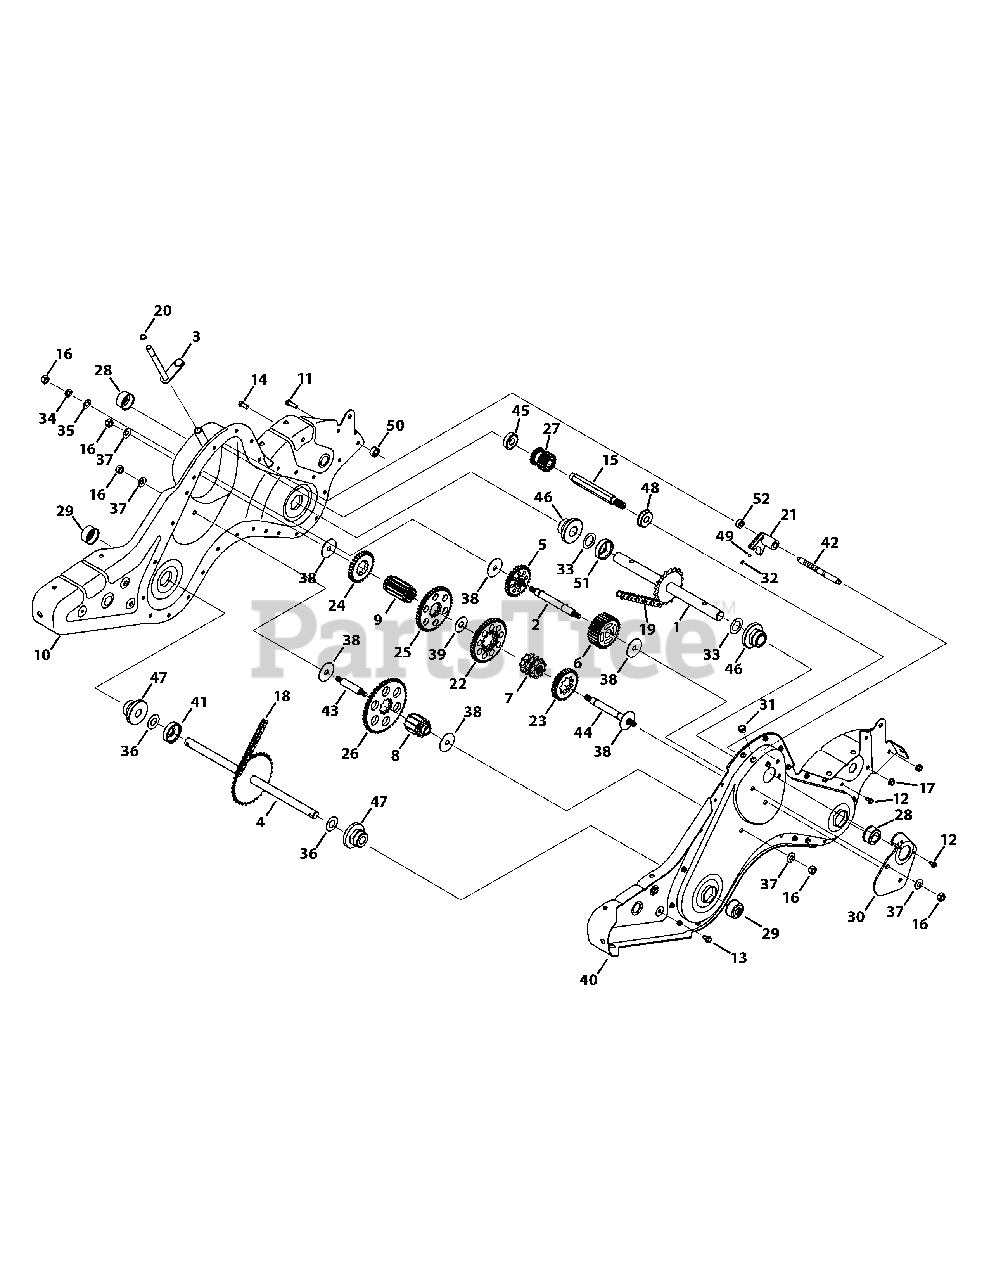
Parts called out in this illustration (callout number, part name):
1	Tine Shaft Ass’y 18T
2	Jack Shaft Ass’y
3	Input Shaft Ass’y
4	Wheel Shaft Ass’y 33T
5	Rev. Idler Gear Ass’y 30T
6	Fr. Idler Gear Ass’y 30 T
7	Tine Input Sprocket Ass’y 9T
8	Wheel Input Sprocket Ass’y 10T
9	Gear Ass’y 11T
10	RH Housing Ass’y
11	Hex Scr 5/16 X 1.00 Gr. 5
12	Hex Wash S-Tapp Scr 1/4-20 x .50
13	Hex Wash HD Scr 5/16-18 X .62
14	Hex Bolt 5/16-18 x .75" Lg. Gr. 5
15	Input Shaft
16	Hex Nut 7/16-20
17	Hex Flange L-Nut 5/16-18
18	#420 Chain 1/2 Pitch x 50 Links-Endless
19	#50 Chain 5/8 Pitch x 54 Links
20	Snap Ring
21	Shifting Fork
22	Spur Gear 44T
23	Spur Gear 30T
24	Spur Gear 30T
25	Spur Gear 44T
26	Spur Gear 44T
27	Spur Gear 16T
28	Seal 1.0" Shaft
29	Seal .75 Shaft
30	Gear Positioner Bracket
31	Taper Cap Plug
32	Compression Spring .230" Lg.
33	Flat Washer 1.03 ID X 1.62 OD X .03
34	Flat Washer .474 x .879 x .064
35	Flat Washer .474 x .879 x .064
36	Flat Washer .76 ID X 1.5 OD X .03
37	Bell. Washer .45" ID x 1.0 OD
38	Thrust Wash. .445 ID x 1.92 OD
39	Flat Washer .635" ID x 1.59 OD
40	LH Chain Case Housing
41	Spacer .75" ID x .50" Lg.
42	Detent Shaft 1/2" Dia.
43	Jack Shaft 5/8" Dia. x 2.38
44	Jack Shaft .625 x 5.0
45	Ball Bearing
46	Tine Shaft Brg. 1.002 x 2.50
47	Wheel Brg. .752" x 2.5"
48	Ball Bearing w/snap ring
49	Ball Detent .250 DIA
50	Spacer .315" ID x .375" Lg.
51	Step Spacer
52	Spacer .505 ID x .88 OD
